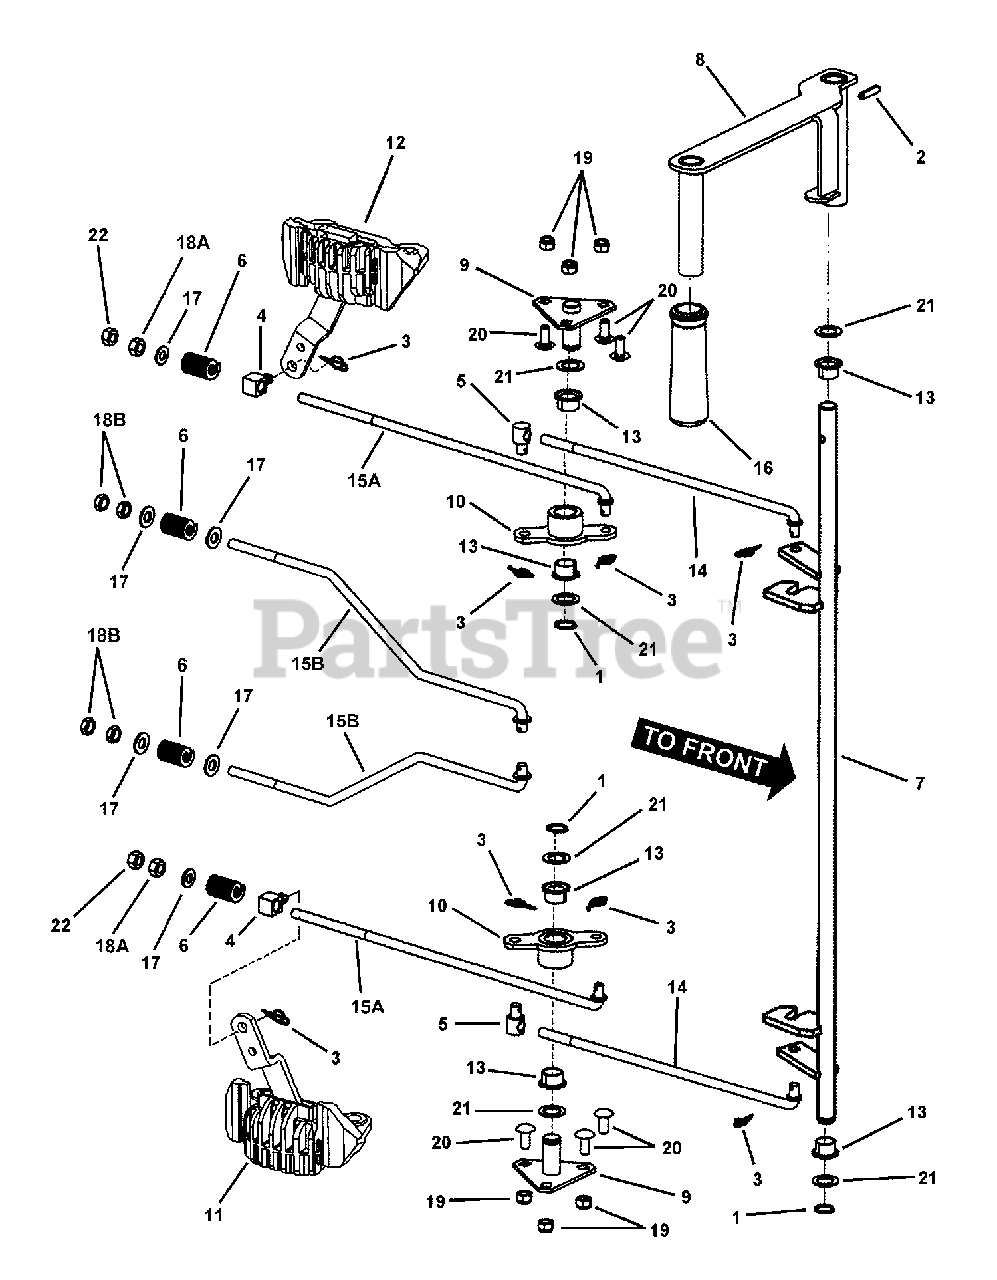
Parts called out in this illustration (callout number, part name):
1	RING, 5/8" External Retaining
2	GROOVE PIN, 1/4 x 1-1/4"
3	PIN, 3/8" Self Locking Cotter
4	SWIVEL, Brake Link-PM
5	SWIVEL, Adjustable
6	SPRING, Rectangular Wire Die, Blue
7	WELDMENT, Brake Rod
8	WELDMENT, Park Brake Handle
9	WELDMENT, Brake Linkage Pivot
10	WELDMENT, Brake Linkage Bellcrank
11	PACKAGE, Left Hand Disc Brake
12	PACKAGE, Right Hand Disc Brake
13	BUSHING, Teflon Impregnated
14	LINKAGE, Park Brake, Front (3/8-24 thread)
15A	LINKAGE, Park Brake, Rear (3/8-24 thread)
15B	ROD, Brake, Rear (3/8-16 thread)
16	GRIP, Parking Brake
17	WASHER, 3/8" Flat
18A	NUT, 3/8-24 Hex Jam
18B	NUT, 3/8-16, Hex Jam, GR 5 or B
19	NUT, 5/16-18 HEX NYLON LOCK
20	BOLT, 5/16-18 x 3/4" Short Neck Carriage, GR 5
21	WASHER, .64 I.D. Flat
22	NUT, 3/8-24 Hex Nyloc
